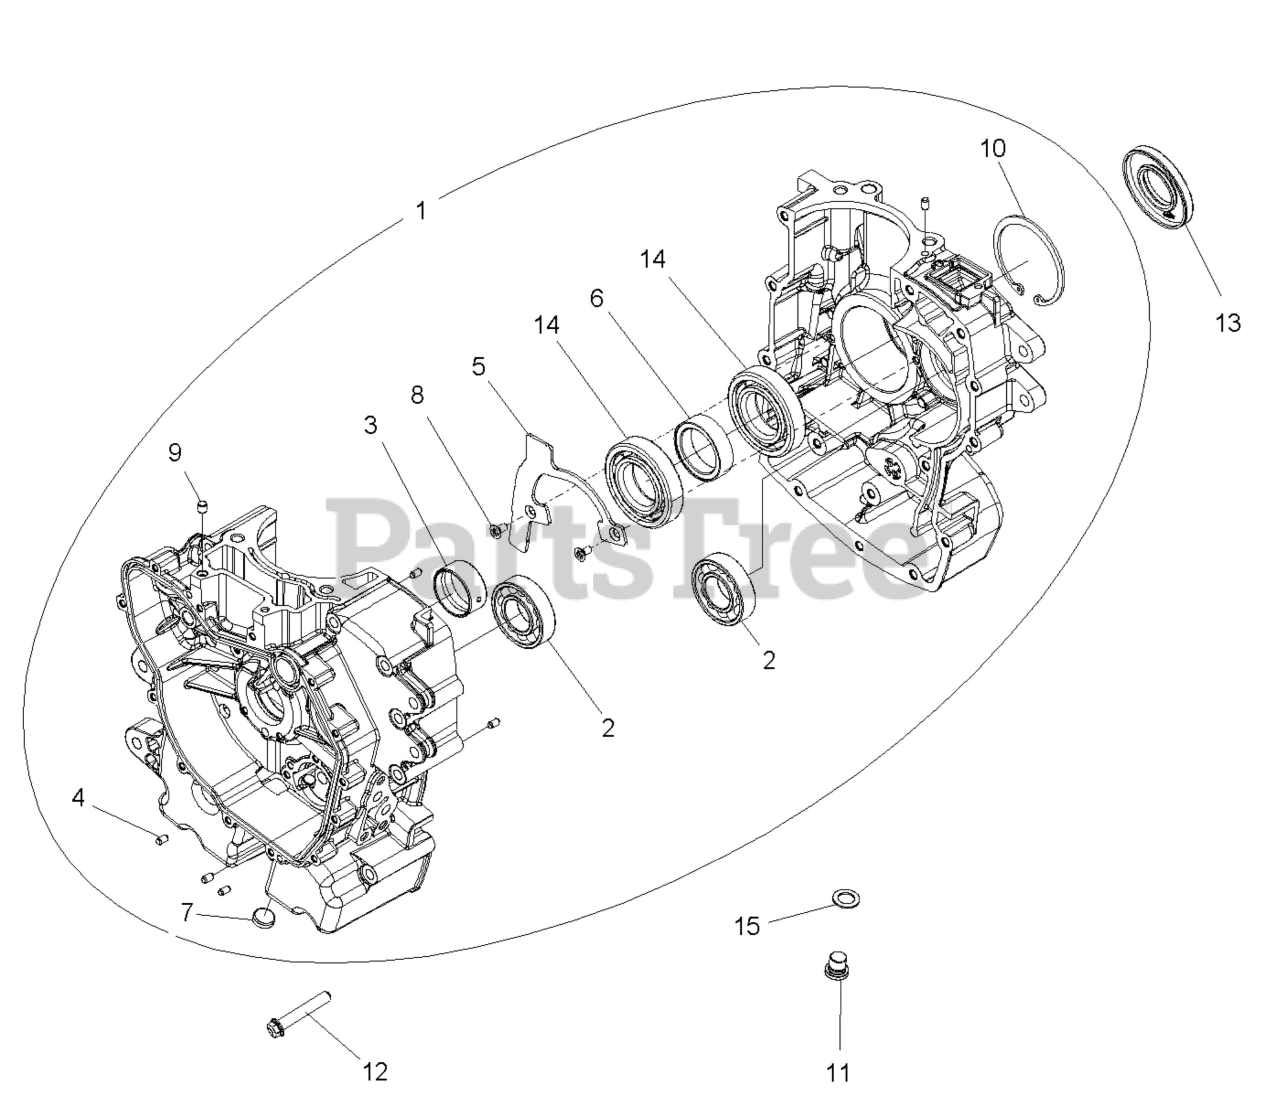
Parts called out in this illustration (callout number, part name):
1	KIT, CRANKCASE
2	BEARING-BALL,30X62X16
3	BEARING, MAIN
4	PIN-DOWEL,M6X10
5	PLATE-BEARING RETAINER
6	SPACER, BEARING
7	PLUG,EXPANSION,19MM
9	DWL-HOL,M8X10
10	RING-SNAP,80X2.5
11	PLUG-SOCKET,M12X1.5 DIN 908A
12	SCR-M8X1.25X90
13	SEAL-CRANKSHAFT
14	BEARING-BALL 40X80X18 DG NCAGE
15	WASHER-19X12X1.3-COPPER (10)
